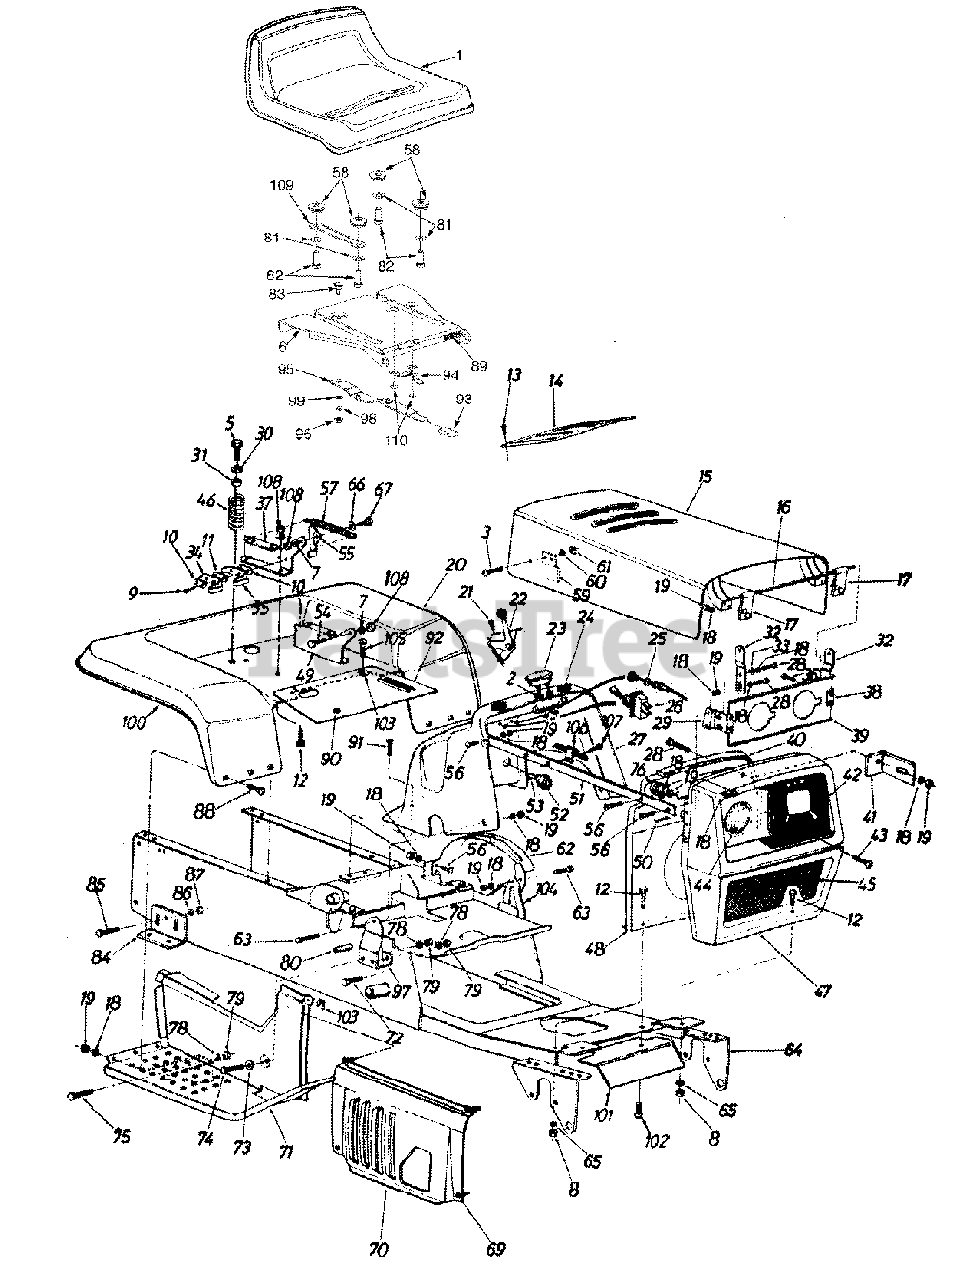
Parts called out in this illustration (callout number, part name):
1	Seat Ass'y.
2	L-Wash. .190" I.D.
3	Truss Hd. Mach. Scr. #10-24 x .38"
5	Hex Wash. Hd. Tap Scr. 5/16-18 x .75" Lg.
8	Hex Nut 5/16-18 Thd.
9	Hex Wash. Hd. AB-Tap Scr. #8 x .5" Lg.
10	Insulator Plate
11	Insulator Boss Plate
12	Hex Bolt 5/16-18 x .75" Lg.
13	Self-Tap Oval Hd. Scr. 1/2" Lg.
14	Dash Panel Cover
17	Hood Hinge Ass'y.
18	Bell-Wash. 1/4" I.D.
19	Hex Nut 1/4-20 Thd.
22	Throttle Control
23	Ammeter
24	Rubber Bumper
25	Choke Control
26	Light Switch
27	Dash Panel
28	Hex Bolt 1/4-20 x .62" Lg.
29	Hood Support Brkt. Ass'y.-R.H.
30	Fl-Wash. .344" I.D. x .875"
34	Safety Switch (Seat)
35	Safety Switch (Seat)
38	Hood Support Brkt. Ass'y.-L.H.
41	Heat Shield Brkt.
42	Head Lamp Bezel
43	Truss Mach. Scr. #10-24 x .50" Lg.
44	Head Lamp
45	Grille Screen
46	Compression Spring 4.5" Lg.
50	Truss Mach. Scr. 1/4-20 x .75" Lg.
53	Ignition Key
54	Shld. Bolt .437" Dia. x .162"
55	Seat Lift Bracket
56	Hex Bolt 1/4-20 x .75" Lg.
57	Extension Spring 5.31" Lg.
58	Seat Spacer
61	Hex Nut #10-24 Thd.
62	Speed Control Guide
63	Truss Mach. Scr. 1/4-20 x .75" Lg.
66	Spr. Wash. .445" I.D. x .75"
67	Shld. Bolt .437" Dia. x .268"
69	Truss Mach. Scr. #10-24 x .5" Lg.
73	Fl-Wash. .385" I.D. x .62" O.D.
74	Hex Bolt 3/8-16 x 3.00" Lg.
75	Hex Bolt 3/8-16 x 1.00" Lg.Grade 5
76	Snap Bushing
78	L-Wash. 3/8" I.D.
79	Hex Nut 3/8-16 Thd.
80	Spacer .375" I.D. x .62" O.D. x 2." Lg.
81	Fl-Wash. .406" I.D. x .875" O.D.
82	Hex Bolt 3/8-16 x 1" Lg.
83	Shld. Bolt 1/4-20 Thd.
84	Transaxle Support Brkt.
85	Rd. Hd. Rib Neck Scr. 3/8-24
86	L-Wash. 3/8" I.D.
87	Hex Nut 3/8-24 Thd. (Gr. 5)
88	Carr. Bolt 1/4-20 x .50" Lg.
89	Compression Spring
90	Snap Bushing
91	Hex Wash. Hd. Tap Scr. 1/4-20 x .5"
94	Seat Stop
95	Seat Lever
96	Lock Nut 1/4-20 Thd.
99	FL. Wash. .344" I.D. x .62" O.D.
100	Trim Strip 84" Lg.
103	Speed Nut #10-24 Thd.
104	Dash Panel Mtg. Brkt.-L.H.
105	Truss Mach. Scr. #10-24 x .5" Lg.
107	Self-Tap Scr. 5/16 x .5" Lg.
108	Hex Nut 5/16-18 Thd. (Gr. 5)
109	Seat Selector
110	Hex B-Tapp Scr. #10-16 x .38" Lg.
